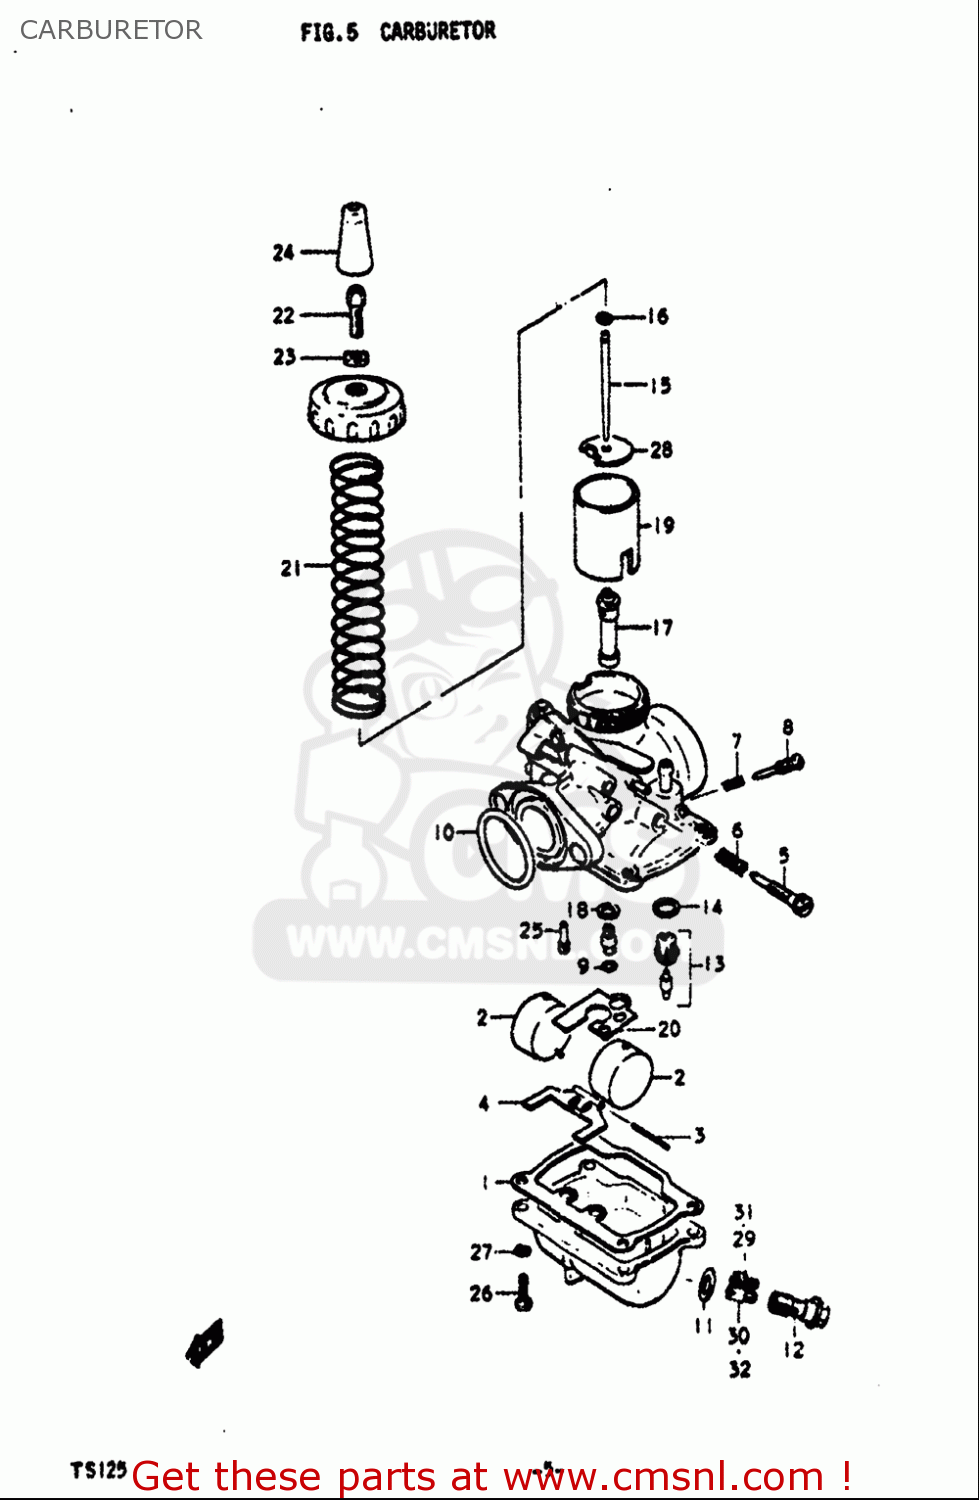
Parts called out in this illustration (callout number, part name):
1	GASKET,FLOAT CHAMBER (NAS)
2	FLOAT
5	SCREW,THROTTLE STOP
6	SPRING,THROTTLE SCREW
7	SPRING
8	SCREW,PILOT AIR
9	O RING
10	O RING
13	VALVE ASSY,NEEDLE
14	GASKET,VALVE SEAT (NAS)
15	NEEDLE,JET
16	CLIP
18	WASHER
20	PLATE
21	SPRING,THROTTLE VALVE
22	ADJUSTER,CABLE
23	NUT
24	CAP
25	JET,PILOT(25)
26	SCREW 4X16
27	WASHER,LOCK
28	SEAT,THROTTLE VALVE SPRING
29	JET,MAIN(90)
30	JET,MAIN(120)
31	JET,MAIN
32	JET,MAIN(140)
